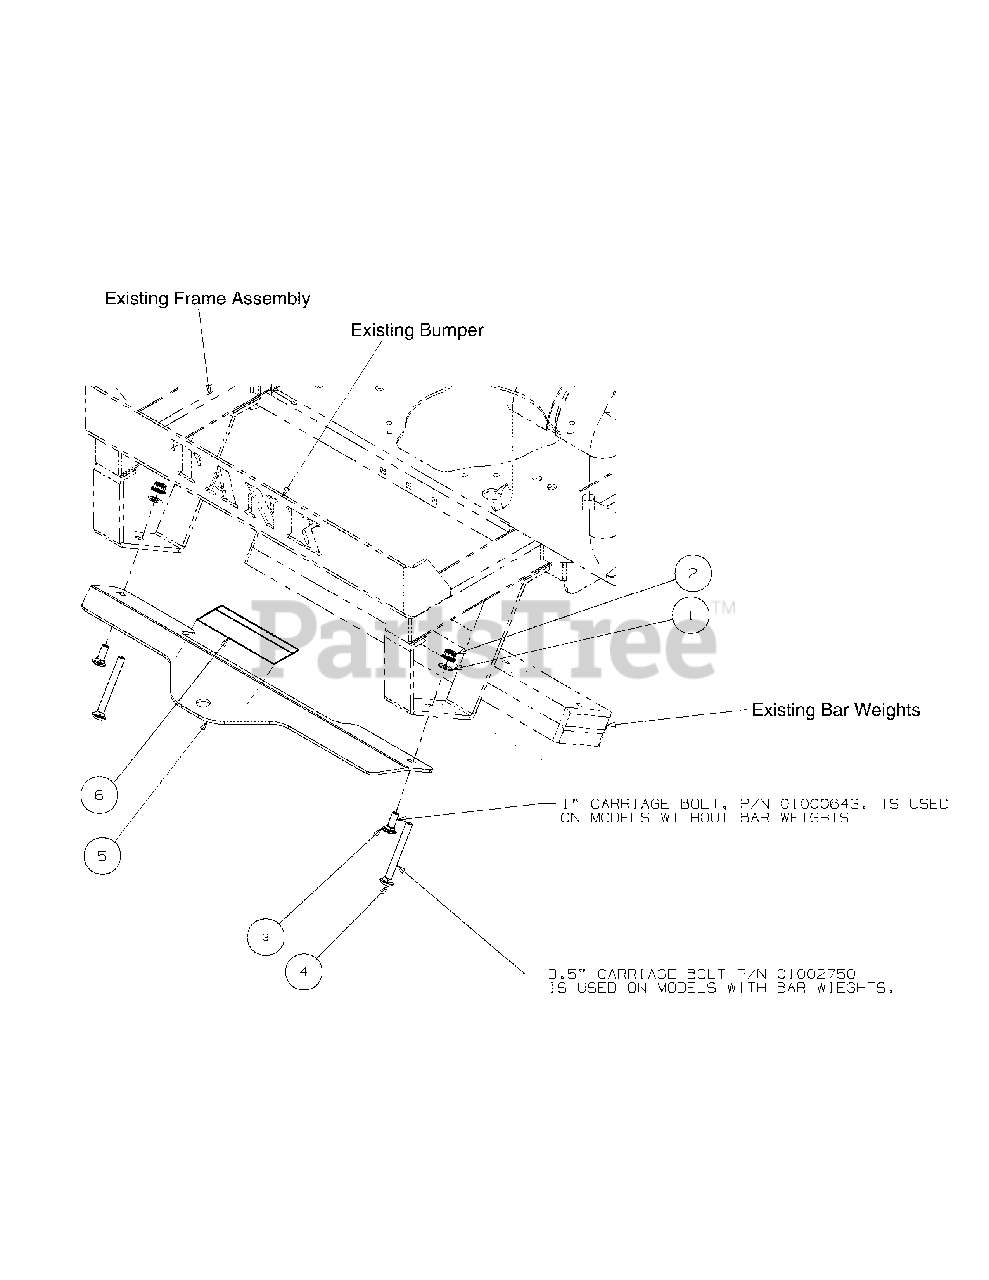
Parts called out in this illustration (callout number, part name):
1	Flat Washer, 3/8
2	Flange Lock Hex Nut, 3/8-16
3	Carriage Bolt, 3/8-16 x 1
4	Carriage Bolt, 3/8-16 x 3.5
5	Hitch
6	Decal, Hitch Warning
